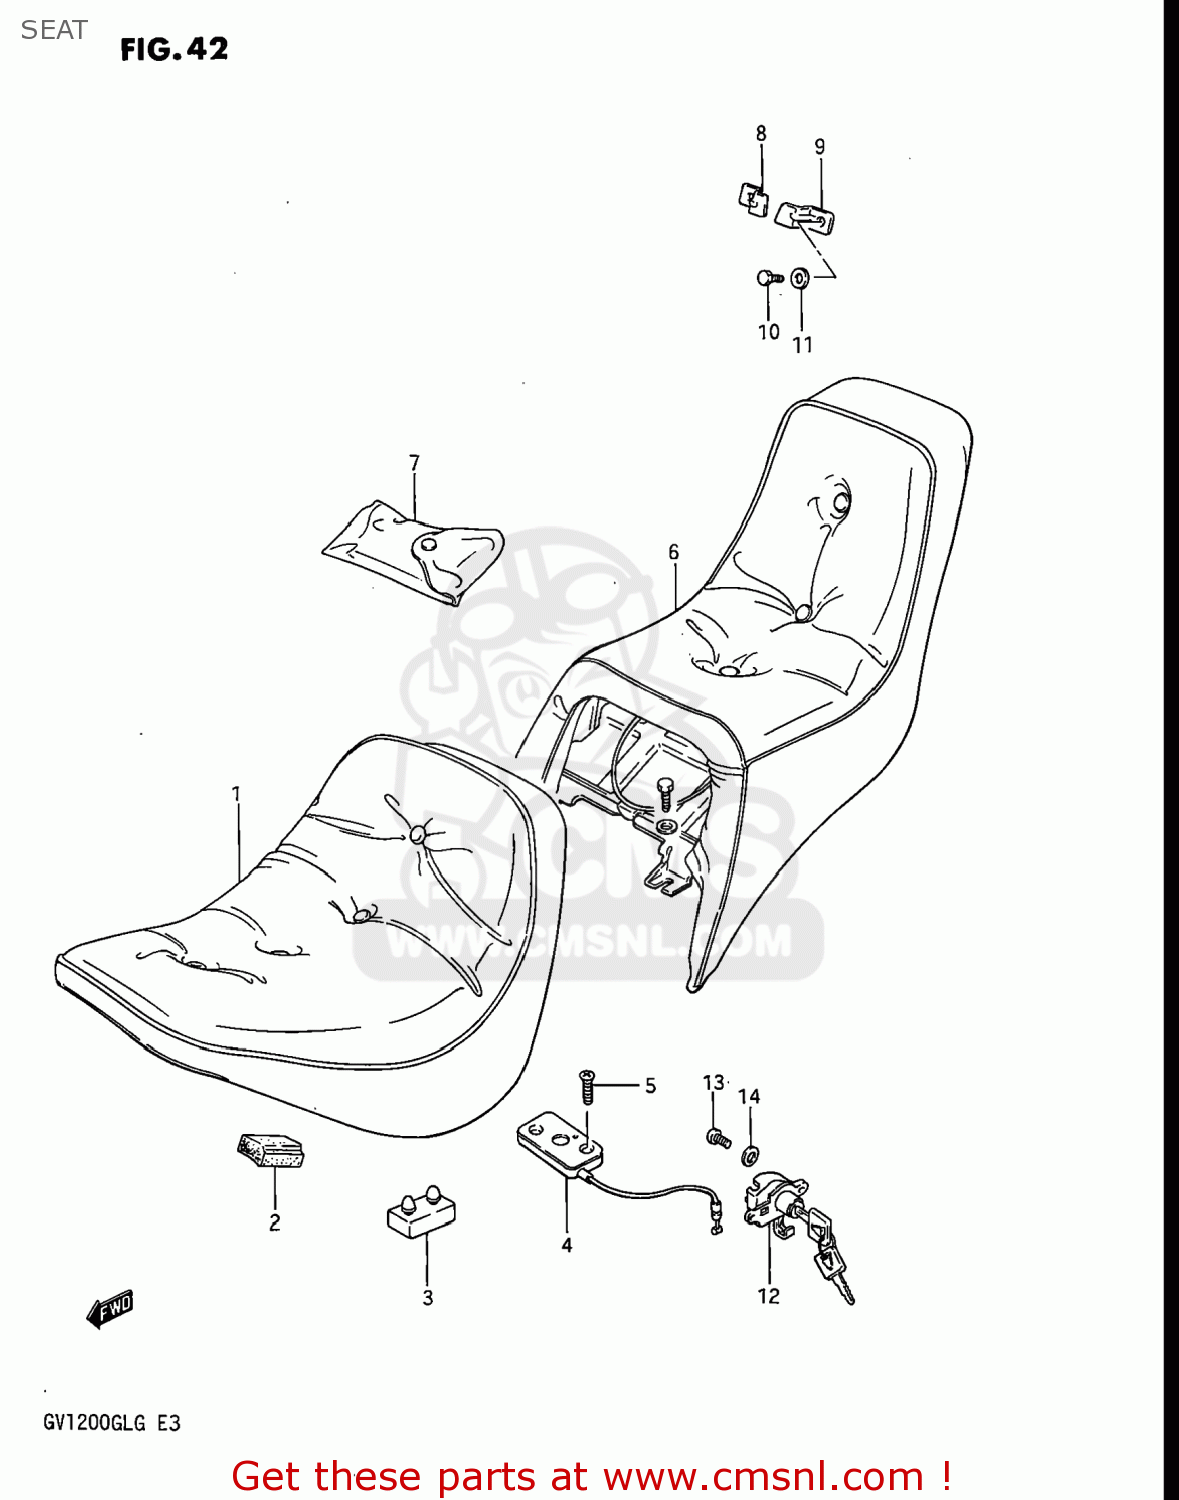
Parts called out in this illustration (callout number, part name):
1	SEAT ASSEMBLY
2	CUSHION,SEAT
3	CUSHION(40X23X12.7)
4	BRACKET,SEAT SUPPORT
5	SCREW
6	SEAT ASSEMBLY,PILLION
7	TOOL ASSY
8	PLATE,SEAT SUPPORT,REAR
9	PLATE,SEAT SUPPORT,REAR
10	BOLT
11	WASHER(6,5X22X1.6)
12	LOCK SET,SEAT
13	SCREW
14	WASHER, LOWER
